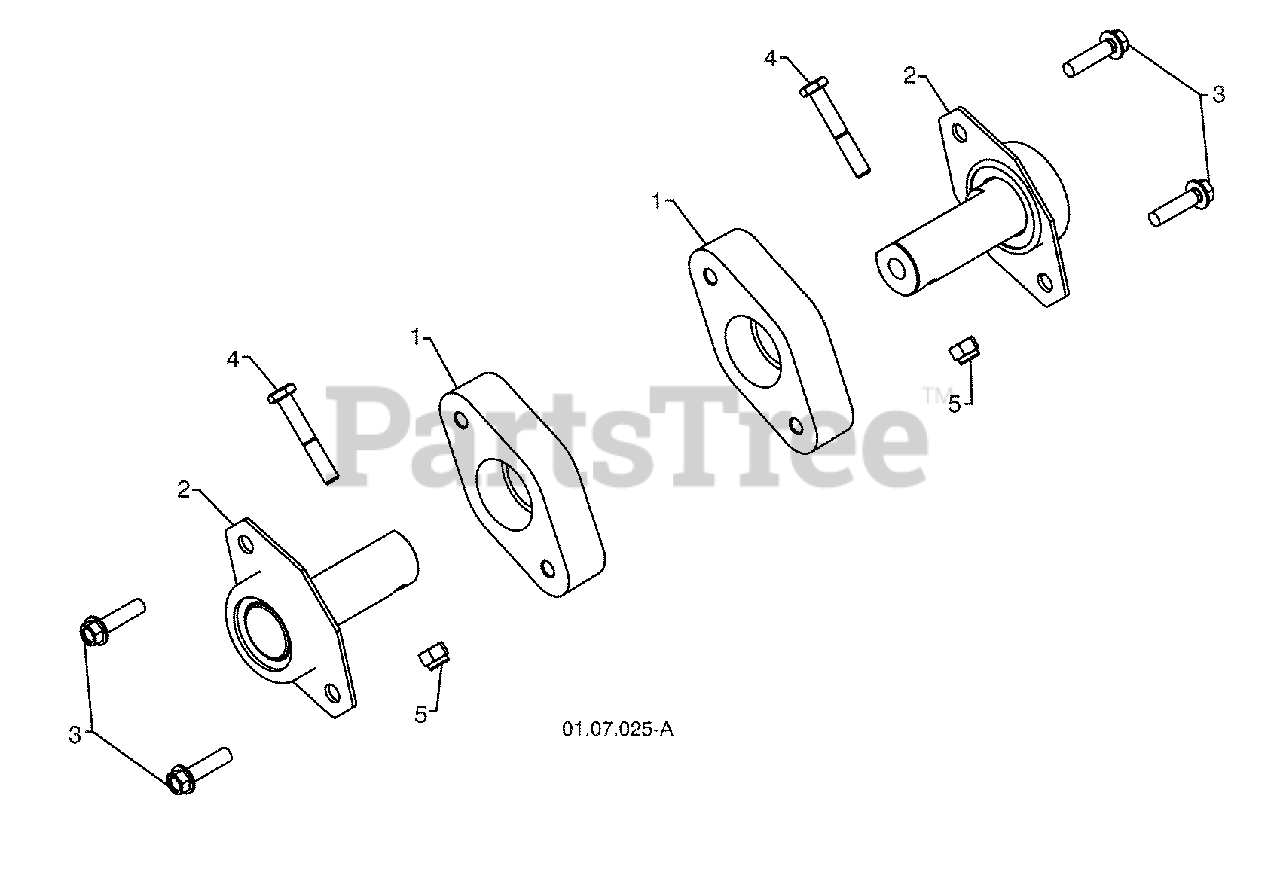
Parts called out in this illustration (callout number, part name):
1	PLASTIC RETAINER
2	AUGER BALL BEARING
3	SCREW 5/16-18 x 1.00
4	SCREW 1/4-20 x .625
5	NUT 1/4-20
